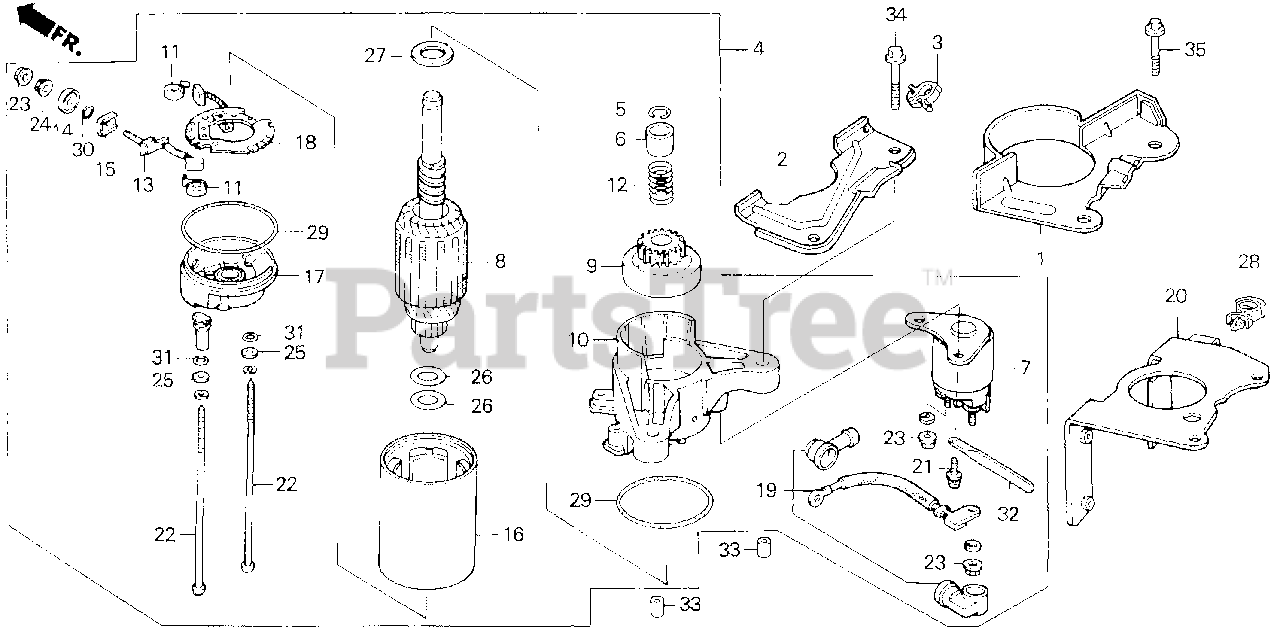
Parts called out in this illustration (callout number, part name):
1	PLATE, SIDE
20	STAY, STARTER
28	CLIP, WIRE HARNESS
35	BOLT, FLANGE (8X28)
